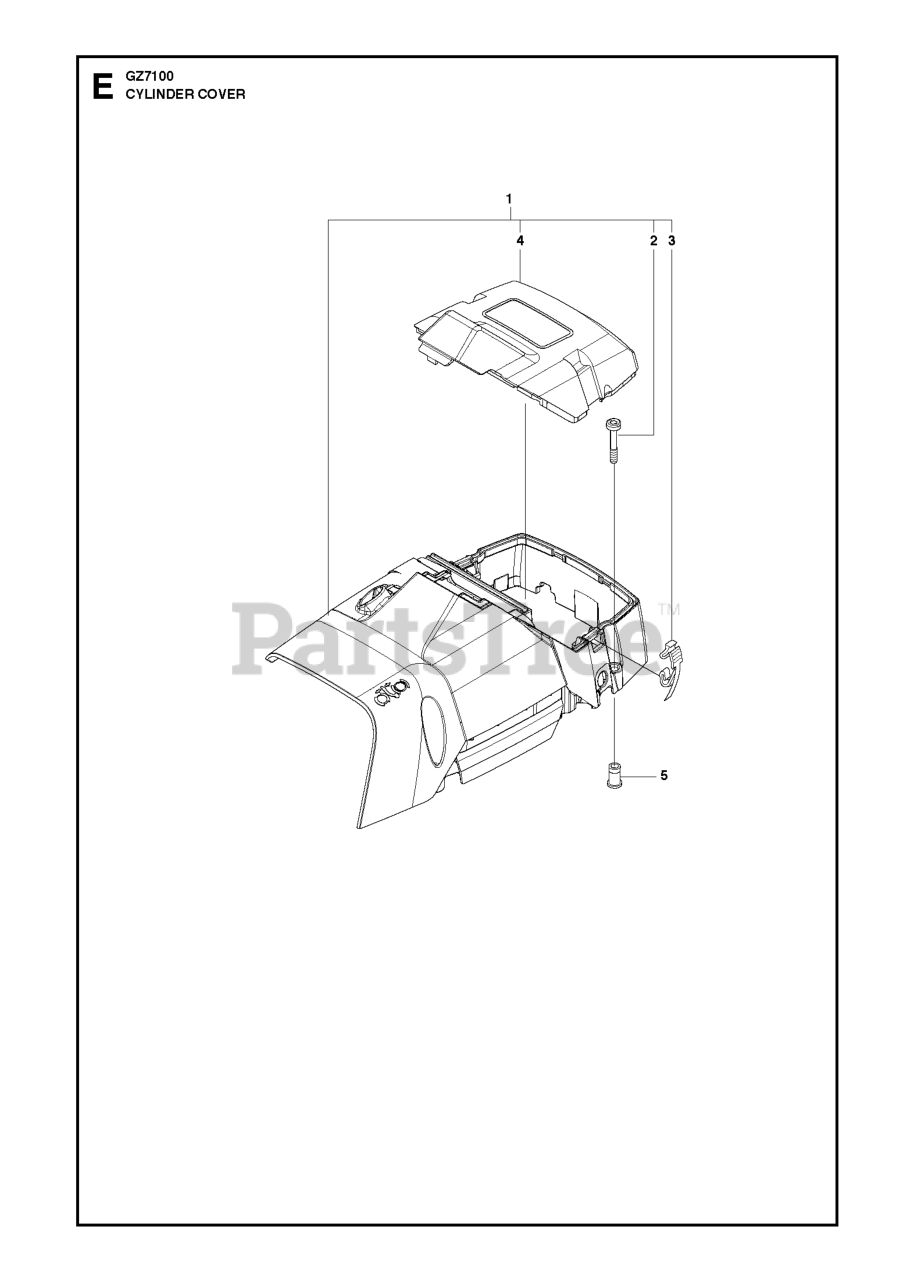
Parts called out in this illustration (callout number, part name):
1	CYLINDER COVER ASSY GZ7100 SPA
2	SCREW CITXPANMO
3	CLIP
4	FILTER COVER ZENOAH /REDMAX
5	SLEEVE CYLINDER
